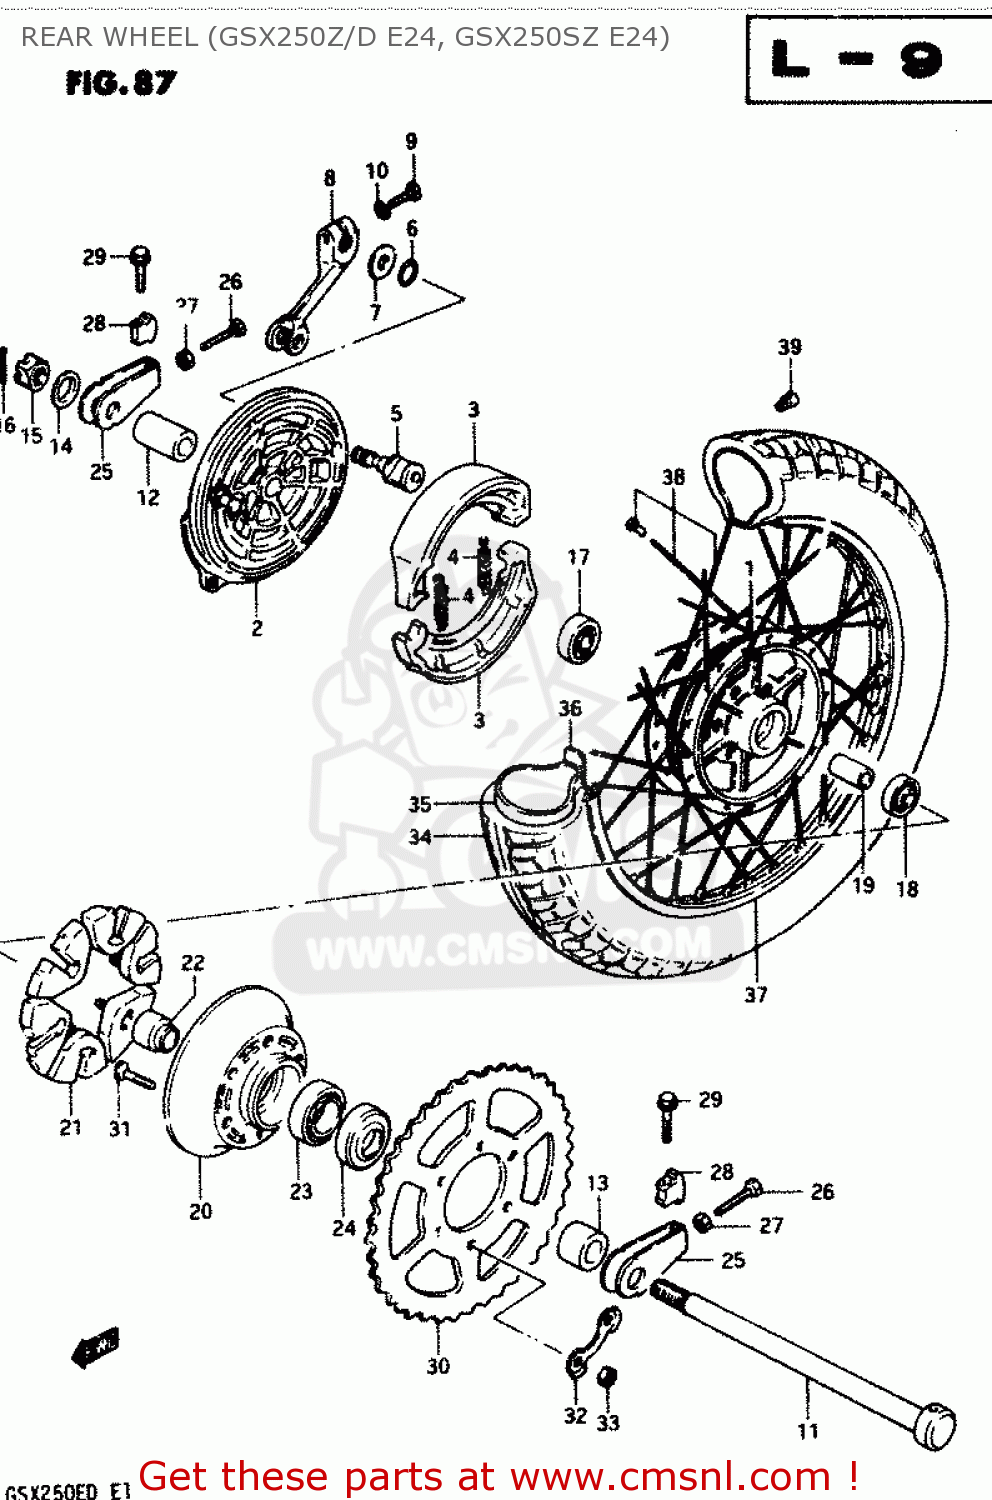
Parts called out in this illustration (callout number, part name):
1	DRUM,REAR HUB
2	PANEL,REAR HUB
3	SHOE,BRAKE
4	SPRING,BRAKE SHOE
5	CAM,FRONT BRAKE
6	O-RING,BOSS
7	WASHER (15X24X1.6)
8	LEVER,RR BRAKE CAM
9	BOLT
10	LOCK WASHER
11	AXLE,REAR
12	SPACER(17.5X28X44.8)
13	SPACER(17X30.5X22.3)
14	WASHER (17X30X3.2)
15	NUT
16	PIN,COTTER
17	BEARING
18	BEARING
19	SPACER (17.6X24X57)
20	DRUM,REAR SPROCKET MOUNT
21	ABSORBER,RR HUB SHOCK
22	SPACER,REAR HUB BEARING
23	BEARING
24	SEAL,OIL(30.5X52X8)
25	ADJUSTER,CHAIN
26	BOLT 8X50
27	NUT
28	SUPPORTER,CHAIN ADJUST
29	BOLT
30	SPROCKET,RR NT
31	BOLT
32	WASHER
33	NUT
34	TIRE
35	TUBE ASSEMBLY,WHEEL,INNER
36	PROTECTOR,INNER TUBE
37	RIM,RR WHEEL
38	SPOKE SET,RR
39	BALANCER,WHEEL (B)
